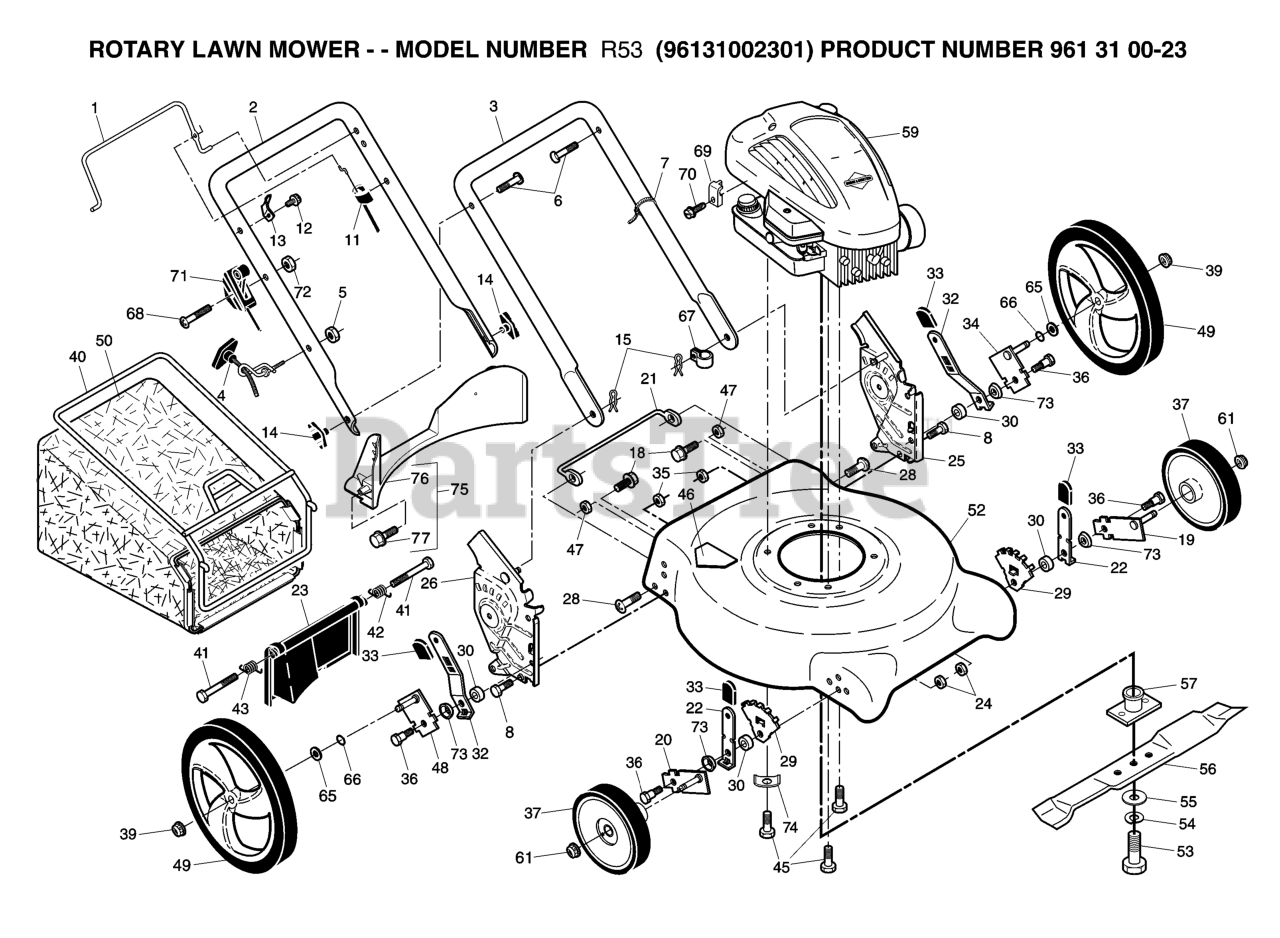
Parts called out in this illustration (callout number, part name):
1	BAIL.MZR.STD.BLACK
2	Upper Handle
3	HANDLE.LOWER.GREY
4	RB GUIDE.ROPE.STD.BLK.ZIN WSL
5	NUT
6	BOLT, HANDLE 5/16-18X1.75
7	TIE GUIDE
8	BOLT.FIN.HEX.5/16-18X3/4
11	ENGINE ZONE CONTROL
13	BRACKET UPSTOP
14	KNOB, DEFLECTOR
15	HAIRPIN COTTER
18	SCREW 1/4X20
19	AXLE ARM ASSY FRONT LH
20	AXLE ARM ASSY FRONT RH
22	SELECTOR SPRING, FRONT
23	REAR DOOR ASSY
24	LOCKNUT 5/16-18
25	RP BRKT.ASM.HAND.HW.21.LT.ORNG
26	RP BRKT.ASM.HAND.HW.21RT.ORNG
29	WHEEL ADJ BRACKET FRONT
30	SPACER.HEIGHT.ADJUSTER
32	SPRING.SEL.EXT.21.DOMED.12/14
34	AXLE ARM ASSY REAR LH
35	LOCKNUT 5/16-18
36	SHOULDER BOLT 5/16-18
37	WHEEL AND TIRE ASSY, REAR
39	NUT.HEX.FLANGE.3/8-16.LOCKNUT
40	FRAME GRASSBAG
42	SPRING.LH.22.REAR.DOOR.EZ.EMPT
43	SPRING.RH.22.REAR.DOOR.EZ.
45	BOLT 3/8-16X1-1/8
46	DECAL.INTERNATIONL.CUTFINGER
48	AXLE ARM ASSY REAR RH
49	RP.WHEEL.12X1.75H 3 SPOKE.RAD
52	KIT.HSG.21.PUSH.ORANGE.CE
53	SCREW, HEX HD 3/8-24 X 1-3/8
54	LOCKWASHER
55	WASHER,HARDEN
56	BLADE.21.PUSH
57	ADAPTER.BLADE
61	NUT.HEX.FLANGE.3/8-16.LO(3 2)
65	WASHER.FLAT.1/2
66	O-RING..070X.487.NEOPRENE
67	CLIP.CABLE.BLK
69	CABLE CLAMP(ENGINE)
70	SCREW.HEX.HEAD.WASHER.10-16
71	THROTTLE CONTROL
72	NUT
73	WASHER.CURVED.CYLINDRICAL
74	WASHER.ENGINE.BZP
75	KIT.BAFFLE.REAR.PLASTIC.21.RD
76	BAFFLE.REAR.PLASTIC.21.RD.ECON
77	SCREW.HX.13X.750
